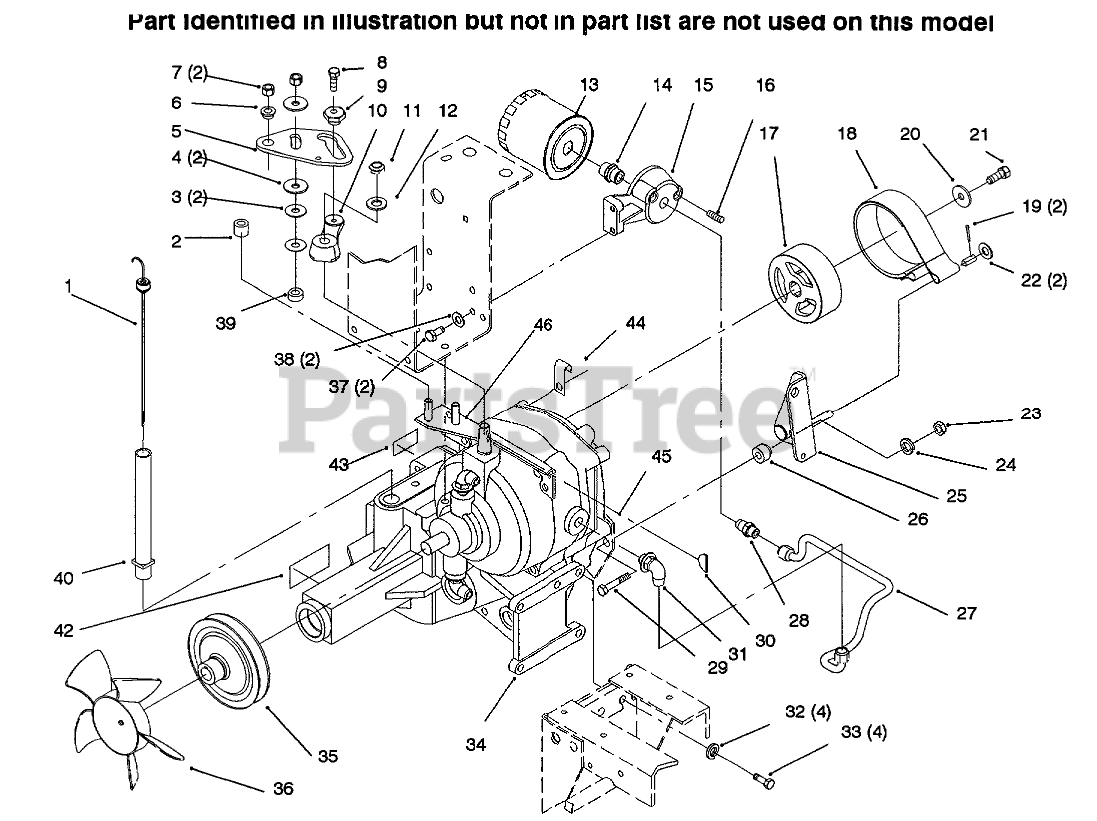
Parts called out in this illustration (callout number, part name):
1	Dipstick
2	Spacer-Pivot
3	WASHER-SPRING DISC
4	FRICTION WASHER
5	CAM-SPEED CONTROL (NS)
6	CAM-SPACER
8	Screw-HH
10	ARM-SPEED CONTROLB
11	NUT-LOCK, NI
12	WASHER-FLAT
13	OIL FILTER ASM
14	FITTING
15	BASE-FILTER
17	DRUM-BRAKE
18	ASSY-BRAKE BAND
19	PIN-COTTER
20	WASHER
21	SCREW-HH, LOCK
22	WASHER-FLAT
23	NUT-LOCK, NI
24	WASHER-FLAT
25	WA-BRAKE PIVOT B
26	BUSHING-BRAKE PIVOT
27	ASS'Y-TUBE FILTER
28	FITTING
29	SCREW-HH
30	KEY-WOODRUFF
31	ELBOW
32	WASHER-LOCK
33	SCREW-HH
34	ASM-Transaxle
35	PULLEY
36	NYLON FAN-L-CW
37	SCREW-HH
38	WASHER-LOCK
39	SPACER-FRICTION
40	NIPPLE-TRANS FILL
42	DECAL - DANGER
43	DECAL-UNIDRIVE
44	CLIP
45	BRACKET-BRAKEB
46	ASSY-PLATE B
